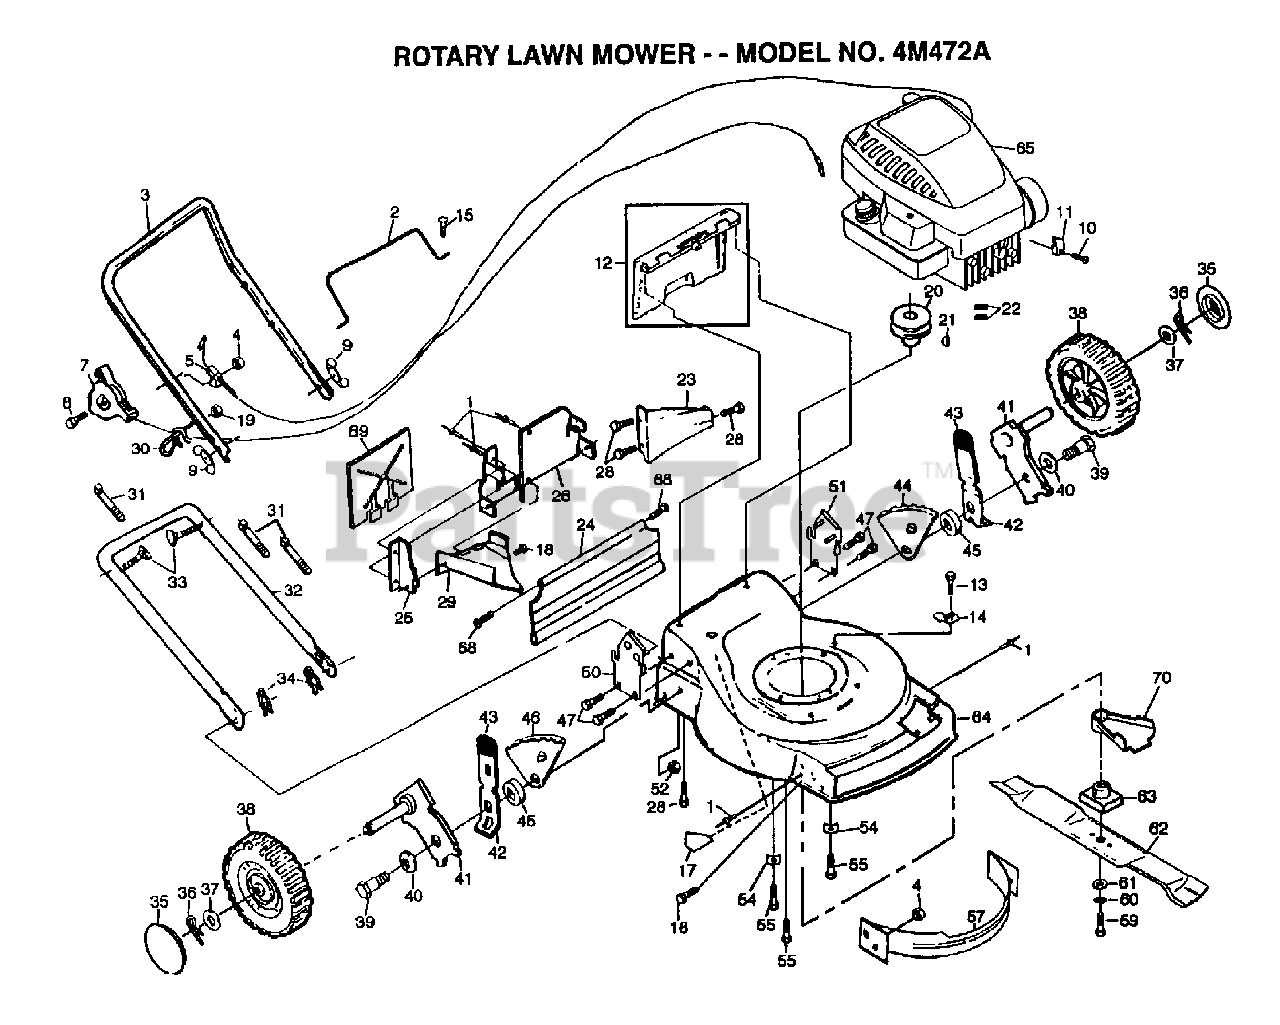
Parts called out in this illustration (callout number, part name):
1	BLIND RIVET
2	CONTROL BAR
5	"CABLE,ENG ZONE CO"
7	"CONTROL, THROTTLE"
8	SCREW.HXHD.WASH.
9	"NUT,WING PM"
10	SCREW PM
11	CABLE CLAMP
12	KIT.DOOR.REAR.22
13	TAPPING SCREW
14	GUIDE CLIP PM
15	"SCREW,PAN HD"
16	SCREW
17	DECAL HYT
18	SCREW PM
19	NUT
20	ENGINE.PULLEY.FWG
21	HI PRO KEY PM
22	SCREW
23	REAR BAFFLE
24	SKIRT.REAR.FGD.22
26	PLATE.BACK
28	SCREW
29	DISCHARGE BAFFLE
30	ROPE GUIDE
33	BOLT.HANDLE.LM
34	HAIRPIN COTTER
35	HUB CAP
36	RETAINER CLIP PM
37	WASHER
38	WHEEL.8X2.PR.RAD.
39	BOLT SHLD 3/8-16
40	"WASHER, BELLEVIL."
41	AXLE ARM
42	SPRING SELECTOR
43	KNOB PM
44	BRACKET.ADJ.9.LH
46	BRACKET.ADJ.9.RH
47	SCREW
52	LOCKNUT PM
55	SCREW
59	SCREW
60	LOCKWASHER
61	"WASHER,HARDEN"
62	"BLADE.MULCH.22"""
63	ADAPTOR.BLADE.LM
64	KIT.HSG.22RD.FWGD
68	HINGE SCREW
69	MULCHER PLATE
